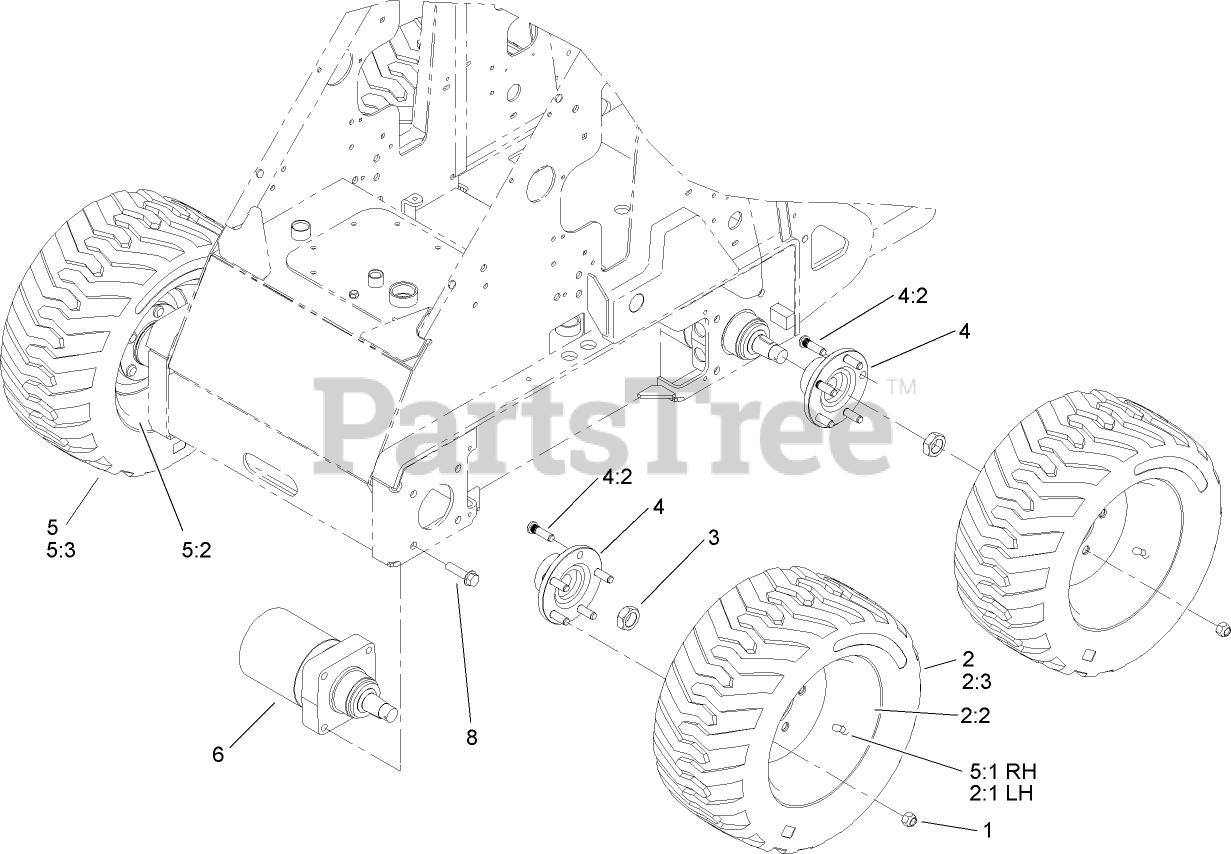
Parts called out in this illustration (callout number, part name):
1	NUT-LUG
2	LH WHEEL AND TIRE ASM
2:1	STEM-VALVE
2:2	WHEEL
3	NUT-LOCK
4	HUB ASM
4:2	STUD-TYPE, DRIVE
5	RH WHEEL AND TIRE ASM
5:1	STEM-VALVE
5:2	WHEEL
6	HYD MOTOR ASM
8	SCREW-HHF
